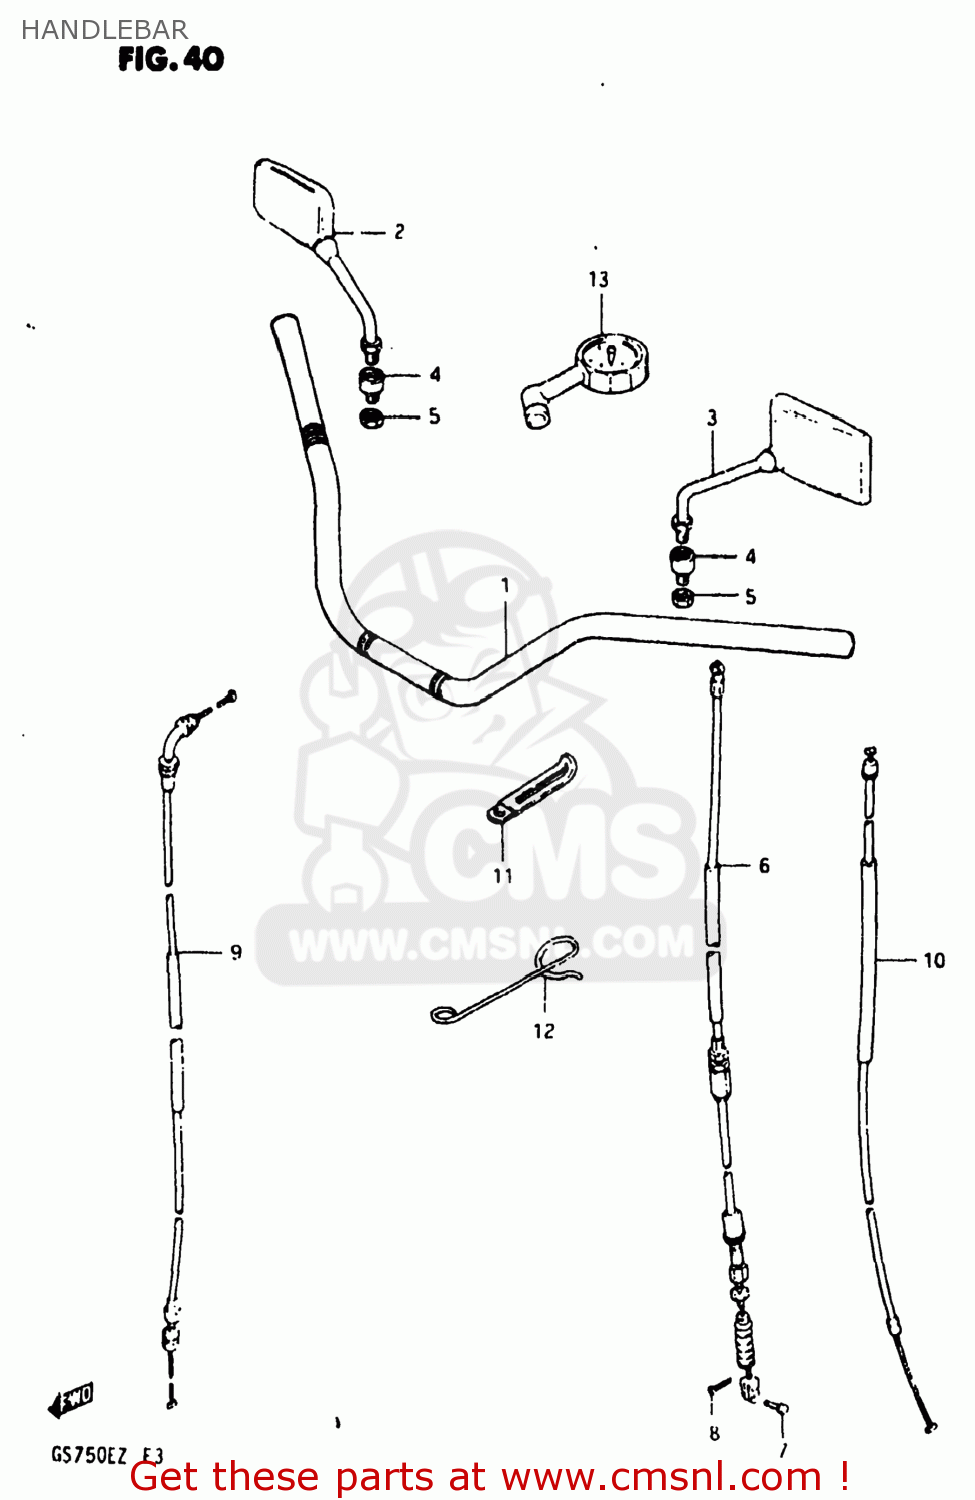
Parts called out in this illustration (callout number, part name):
1	HANDLEBAR
2	MIRROR ASSEMBLY,REAR VIEW
3	MIRROR ASSEMBLY,REAR VIEW
4	CUSHION ASSY,RR VIEW MIRROR
5	NUT
6	CABLE ASSEMBLY,CLUTCH
7	PIN(L:15)
8	PIN
9	CABLE ASSEMBLY,THROTTLE
10	CABLE,STARTER
11	CLAMP
12	GUIDE,CLUTCH CABLE
13	GAUGE ASSY,AIR PRESSURE
